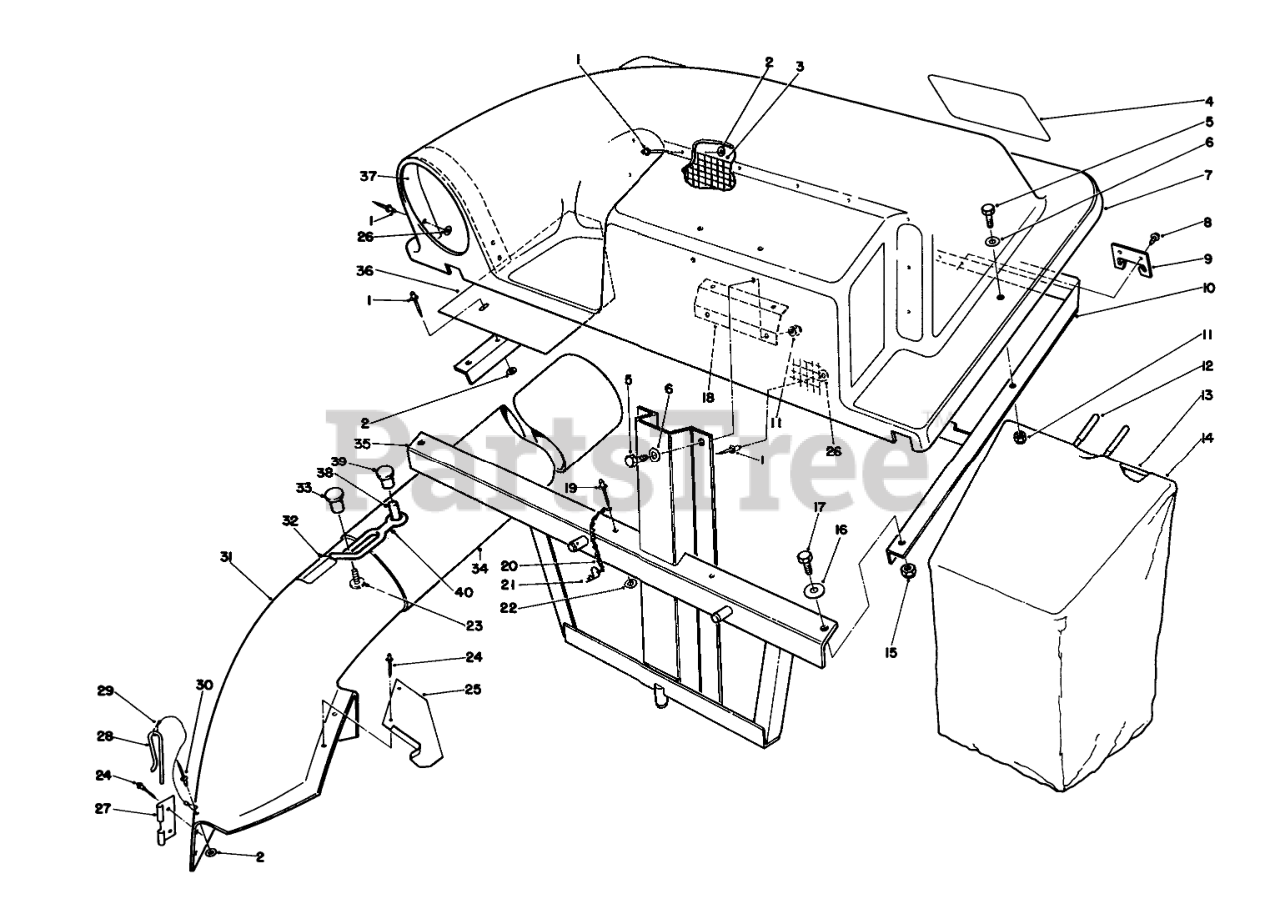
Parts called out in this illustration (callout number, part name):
1	RIVET-POP
2	WASHER-PLAIN
3	SCREEN
4	DECAL-BAGGER, TWIN
5	SCREW-HH
6	WASHER-PLAIN
7	COVER-BAGGER, TWIN
8	SCREW-HWH
9	BRACKET-FRAME, BAG
10	Cover-Frame
11	NUT-LOCK, NI
12	GRIP-HANDLE, BAG
13	Frame-Bag
15	NUT-LOCK, NI
16	WASHER-FLAT
17	SCREW-HH
18	Plate-Backup
20	10 LINK CHAIN W/O HOOK
21	PIN-HAIR
22	WASHER-BACK
23	Screw
24	RIVET-BLIND
25	CHUTE SUPT BRKT
26	WASHER-FLAT
27	BRACKET-MOUNTING, CHUTE
28	PIN-LOCKING, CHUTE
29	LANYARD
30	RIVET-BLIND
31	Assembly-Chute (Incl. Ref. #24-30 & 32)
32	DECAL-DANGER
34	Duct
35	Frame-Mounting
36	Baffle
37	Support Inlet
38	SPACER-INTERLOCK
39	FASTENER-PANEL
40	RETAINER-DUCT
